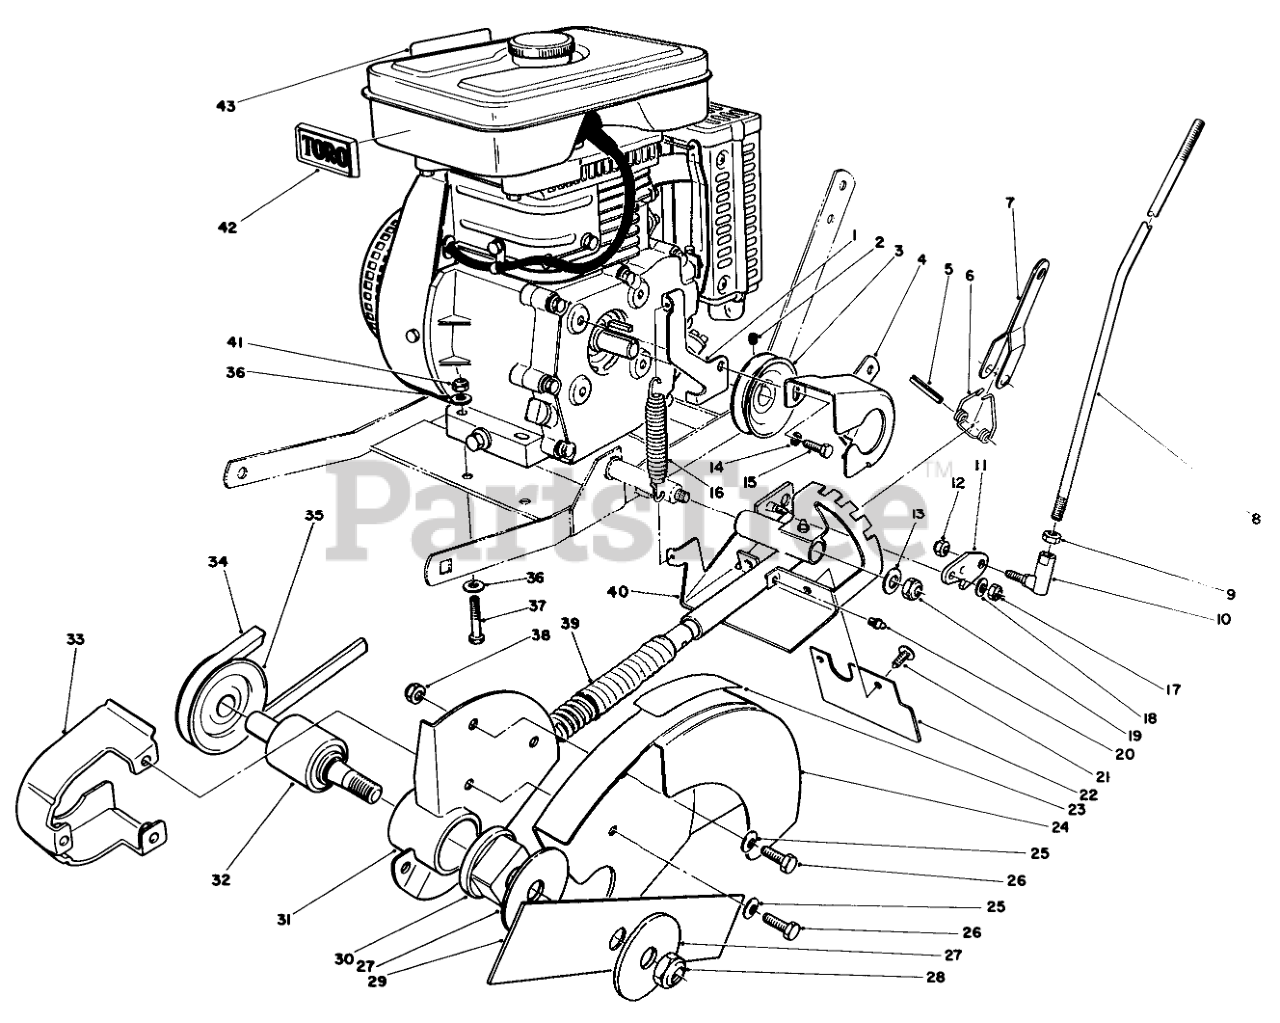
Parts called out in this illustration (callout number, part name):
1	SPRING BRKT R
2	SCREW-SET
3	PULLEY (3.5 HP)
4	ENG. PULLEY GUARD
5	PIN-ROLL
6	Spring-Torsion
7	LEVER WA R
8	Rod-Lower
9	NUT-HJ
10	BALL JOINT
11	LEVER LOCK WA
12	NUT-LOCK
13	WASHER-PLAIN
14	WASHER-LOCK
15	SCREW-HH
16	EXT. SPRING
17	NUT-LOCK, NI
18	WASHER-FLAT
19	NUT-LOCK, NI
20	FITTING-GREASE
21	PANEL FASTENER
22	RUBBER GUARD
23	BLADE WARNING DECAL
24	Blade Guard Assembly
25	WASHER-BELLEVILLE
26	SCREW-HWHTF
27	WASHER-LARGE
28	NUT-HEX
29	10" EDGER BLADE B
30	BRG SHIELD
31	HUB ASM
32	Spindle Assembly
33	PULLEY GUARD WA
34	V-BELT
35	PULLEY-SPINDLE ASM
36	WASHER-PLAIN
37	SCREW-HH
38	NUT-HEX
39	SPRING & BELLOW ASM
40	PIVOT WA
41	NUT-LOCK, NI
42	TORO LOGO PLT
43	Decal-Instruction
